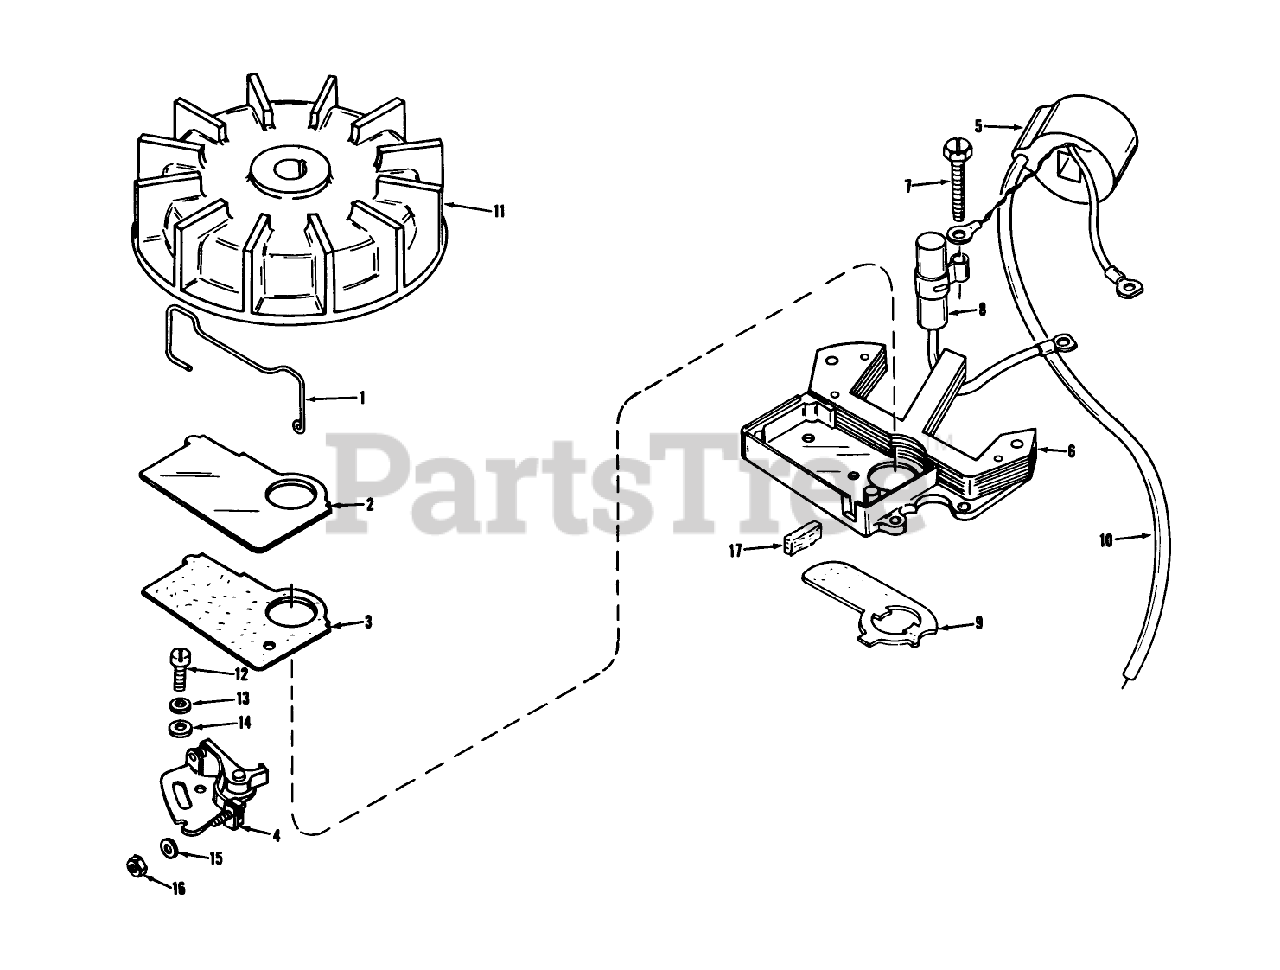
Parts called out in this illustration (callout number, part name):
1	Dust Cover Spring
2	Dust Cover
3	Dust Cover Gasket
4	Hose-Primer 209543
5	Coil Assy.
6	Gasket 209542
7	Condenser Screw
8	Condenser Assy.
9	Sealing Washer
10	STRAP S
11	RETAINER WASHER
12	Fuel Hose
13	Fuel Tank
14	Flatwasher
15	Washer
16	DECAL
17	Cam Felt
